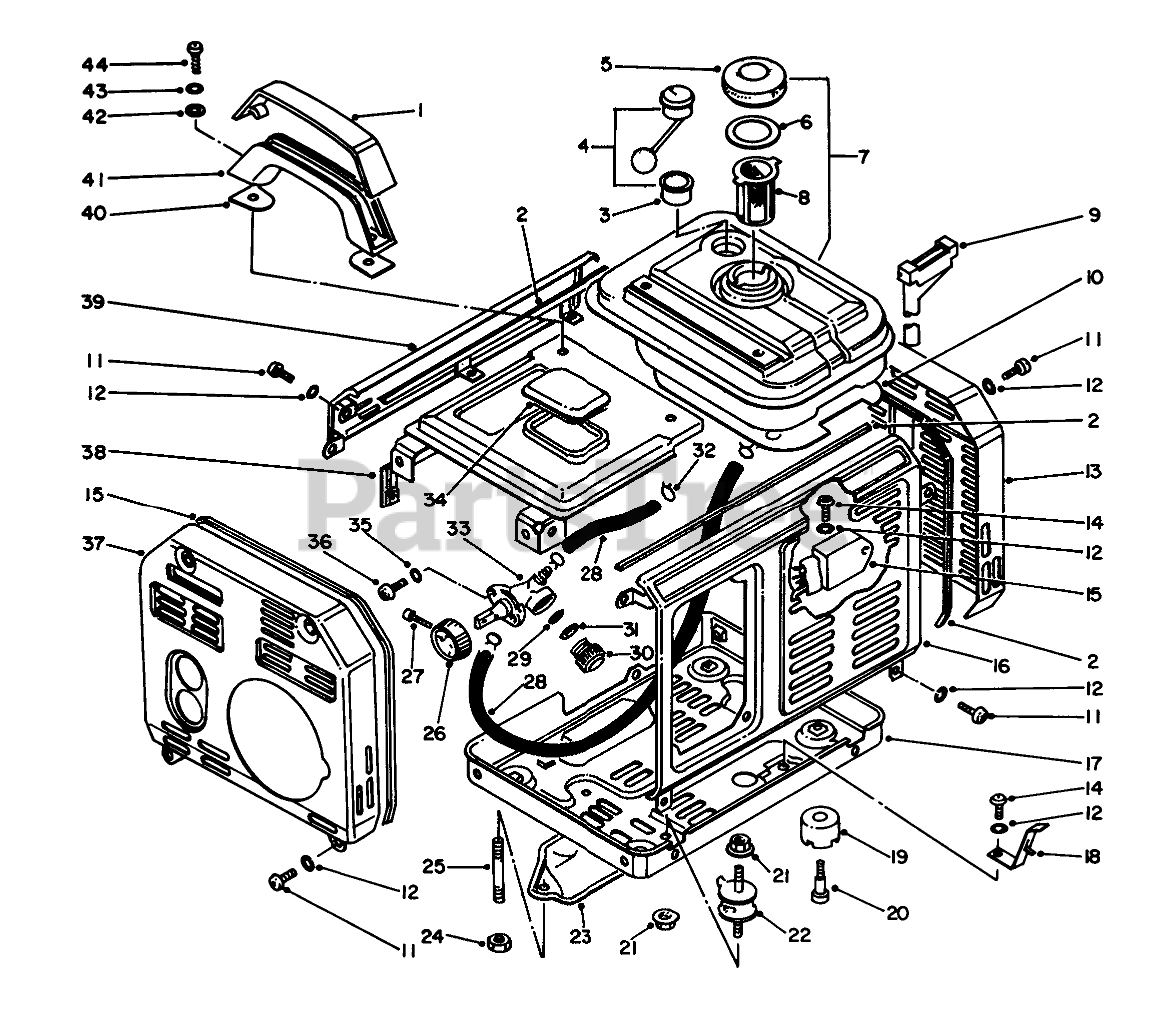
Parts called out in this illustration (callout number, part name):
1	Cover-Grip
3	Gasket
4	Gauge Assembly Fuel
5	FUEL TANK CAP
6	GASKET
7	Tank-Fuel
8	Filter
9	Duct Over Flow
10	Plate-Heat Guard
11	Screw
12	Washer
13	Cover-R.H.
14	Screw
15	Unit-Oil Level Alarm
16	Cover-Front
17	Plate-Engine Mounting
18	Clamp
19	CUSHION
20	Screw
21	M6 X 1 LOCKNUT
22	ENGINE MOUNT
23	Cover-Tool
24	Nut
25	Stud Bolt-Tool Cover
26	Knob-Cock
27	Screw
29	FILTER
31	Gasket
33	Cock Assembly-Fuel
35	Lockwasher
36	Screw
37	Cover-L. H.
38	Cover-Upper
39	Cover-Rear
40	Gasket
42	Washer
43	Lockwasher
44	Screw
